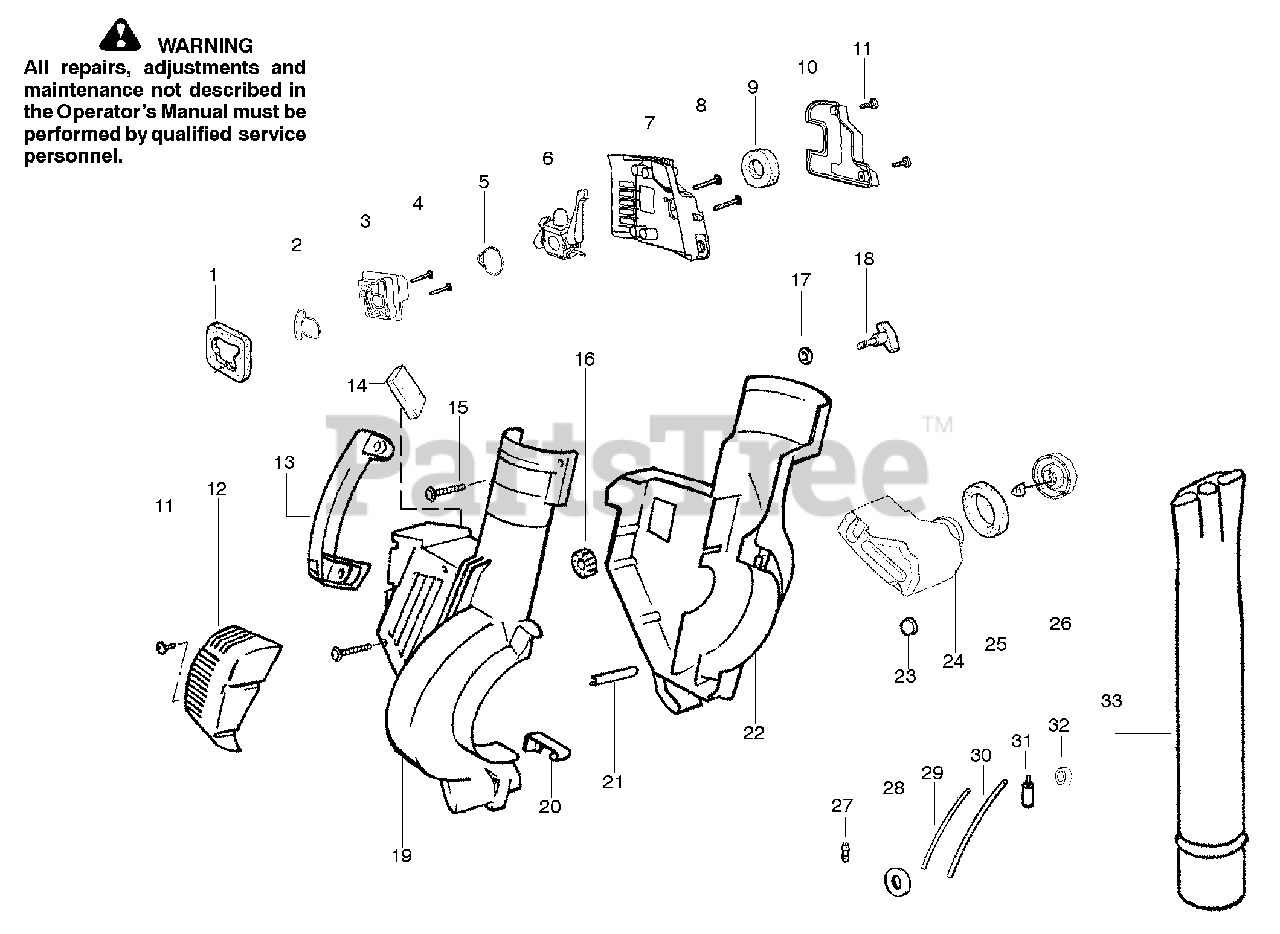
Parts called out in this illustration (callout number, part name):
1	Air Dam (kit)
2	Gasket-Adapter (kit)
3	Carburetor Adaptor
5	Gasket-Carburetor (kit)
6	Kit-Carb Ass’y. Zama-(C1Q-W11C)
6	Kit-Carb Ass’y. Walbro-(WT-606)
10	Cover-Air Filter
12	Guard-Muffler
14	Foam - 71.12mm (kit)
19	Shroud -RH
20	Spring-Cover Latch
21	Guide-Starter Rope
22	Shroud-LH
23	Isolator-Crankcase
24	Assy-Fuel Tank
25	Gasket-Fuel Tank
26	Fuel Cap w/Retainer
27	Fitting-Fuel Line
28	Grommet-Shroud
29	Kit-Line Carb/Purge
30	Kit-Line Tank/Purge
31	Assy-Fuel Pick-up
32	Grommet-Fuel line (kit)
